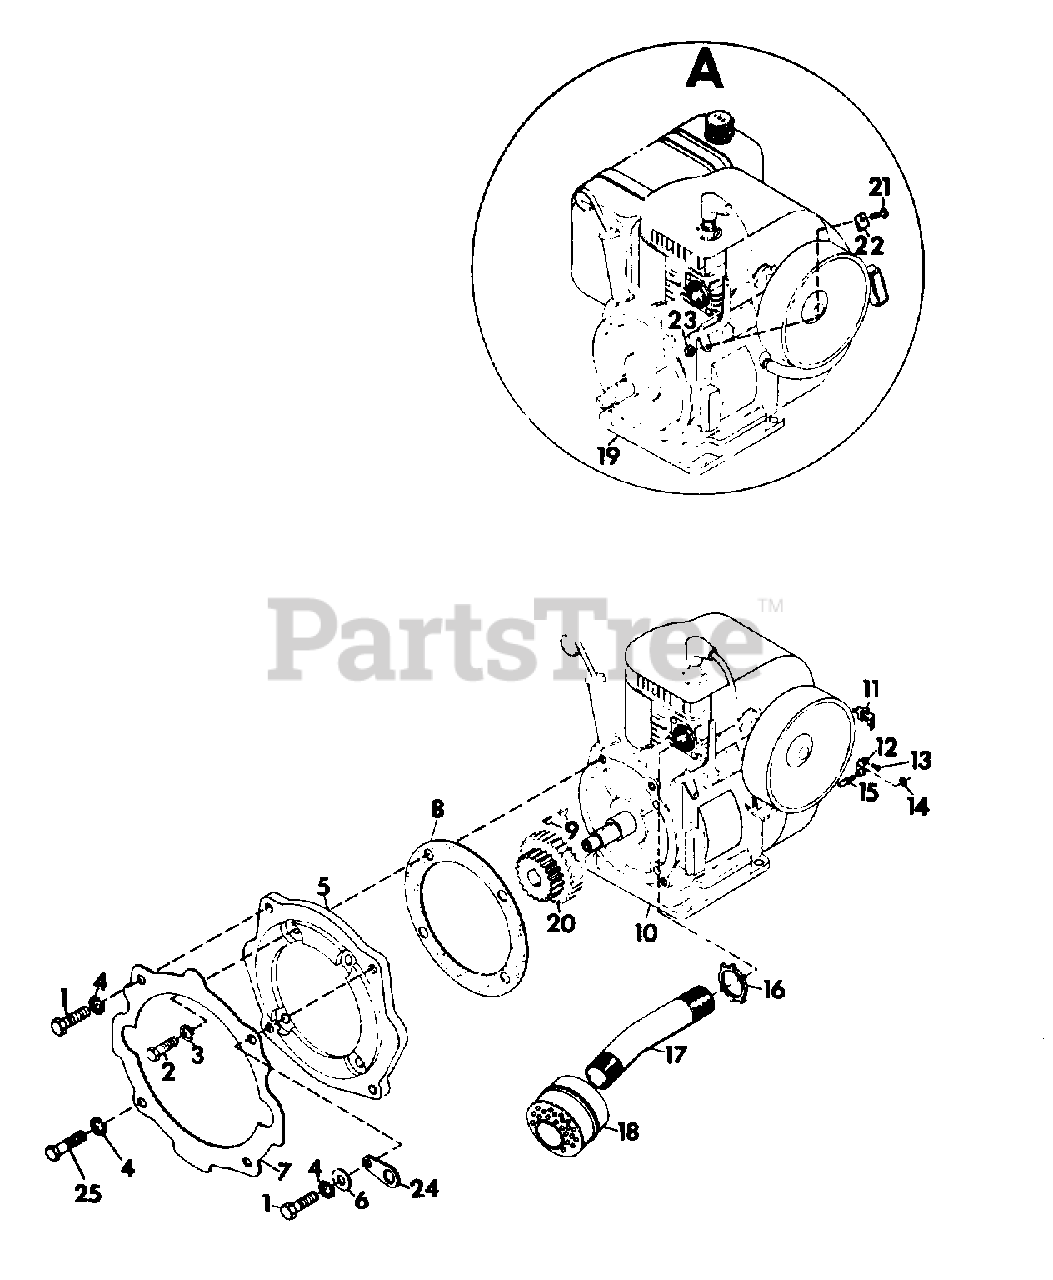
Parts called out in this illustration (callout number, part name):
1	BOLT, HEX; 7/16-14 X 1-1/2
2	BOLT, HEX; 3/8-16 X 1, 12 H.P.
3	WASHER, LOCK; 3/8 SP HEAVY
4	WASHER, LOCK; 7/16 SP HEAVY
5	ADAPTER, ENGINE; 12 H.P.
6	WASHER, FLAT; .469 X .938 X .065
7	GASKET, CHASSIS TO ADAPTER
8	GASKET, ENGINE TO ADAPTER, 12 H.P.
9	KEY, WOODRUFF; 5/32 X 5/8 HARD
10	ENGINE, 12 H.P. 2-WHEEL ELECTRIC
10	ENGINE, 12 H.P. 2-WHEEL MANUAL
11	CLIP, SPEED
12	BRACKET
13	SCREW, MACH; 1/4-20 X 1/2 PAN HD
14	NUT, HEX; 1/4-20
15	ADAPTER, CONDUIT
16	NUT, CONDUIT; 1 PIPE
17	TUBE, MUFFLER, 12 H.P.
18	MUFFLER, 12 H.P.
20	GEAR, 10/12 DP 21/30 TEETH
24	BRACKET, FUEL LINE
25	BOLT, HEX; 7/16-14 X 1-1/4
